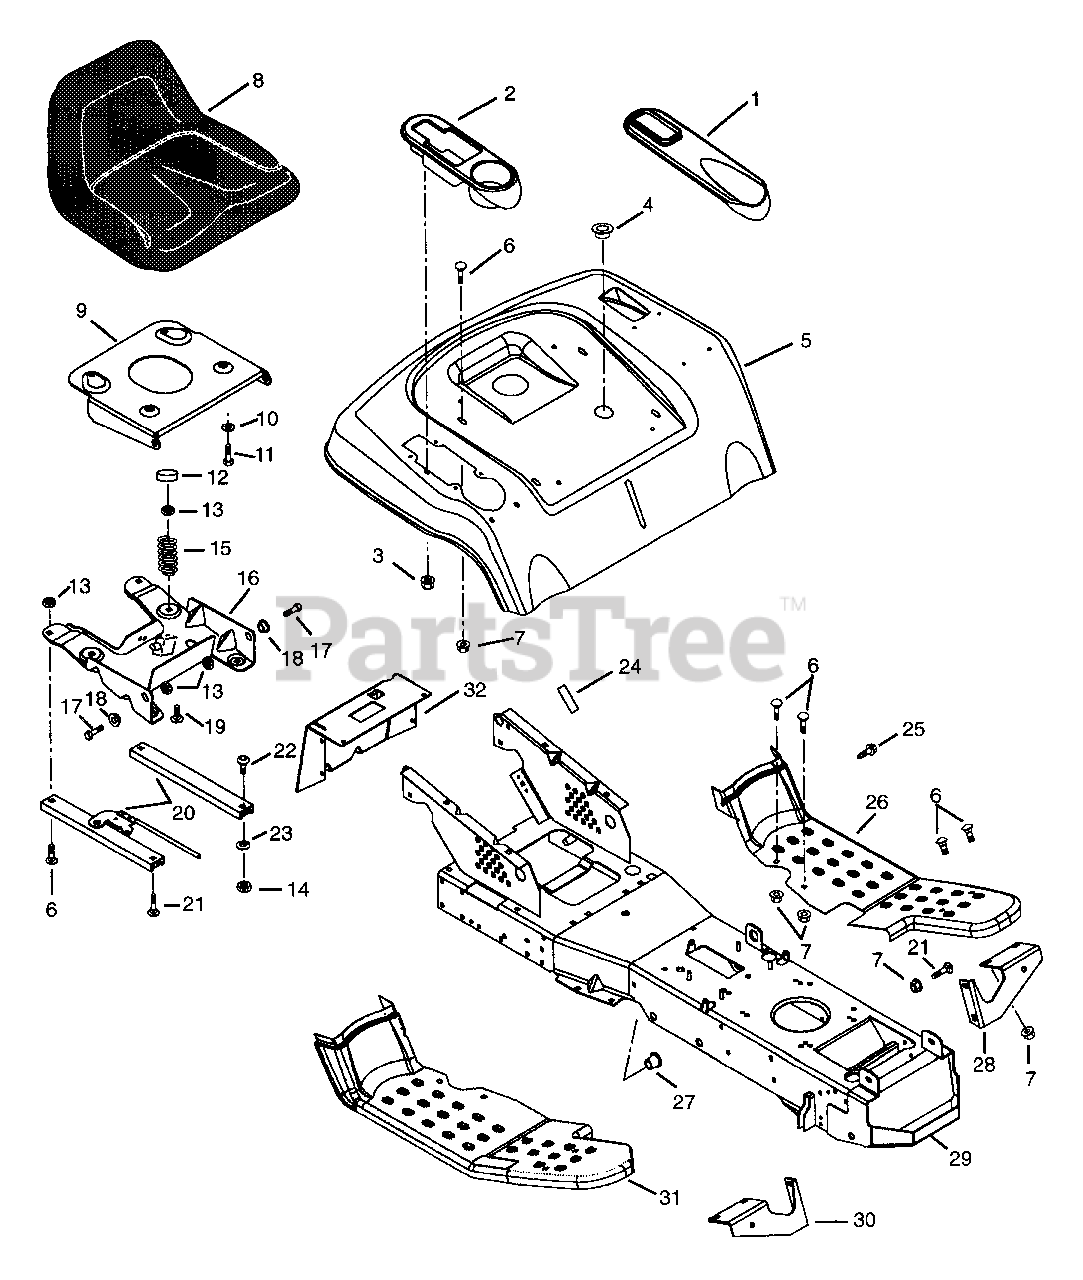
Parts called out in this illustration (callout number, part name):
1	INSERT- LIFT
2	INSERT - BEVERAGE
3	NUT-SELF-THRDNG FITS.25 STUDPL
4	SNAP BUSHING
5	REAR DECK
6	BLT-RDHDSQNK .312-18X.62SHTPL
7	NUT-FLG. .312-18 PL
8	SEAT V-1500 HI WELTLESS
9	SEAT PIVOT PLATE
10	WSHR-LK .312X.097 PL HVY
11	BLT-HEX .31-18X.75 PL GR2
12	TUBE CAP
13	NUT-LK .312-18 GR A PL
14	NUT-HEX .312-18
15	SG-COMP .148X1.23X2.41 WLD87
16	BOX, SEAT
17	BLT-HEX .31-18X.75 PL GR5
18	BSHG-FLG .325X.465X.333X.685
19	BLT-RDHDSQNK.31-18X.75GR5SHTPL
20	SEAT SLIDES -(RAME TAK-3010-4)
21	BLT-RDHDSQNK .31-18X.75 SHT PL
22	SCR-CAP BTHD.31-18X.50 GR5 YZ
23	WSHR-LK-EXT .313X.030 PL
24	PAD,BATTERY
25	SCR-TAP .375-16X .50 HWH PL TR
26	FOOTREST- LH
27	BSHG-FLG .515X.750X.745X1.00NY
28	BRACE - FOOT REST L.H.
29	FRAME, MAIN
30	BRACE - FOOT REST R.H.
31	FOOTREST- RH HYDRO
32	DRAWBAR
